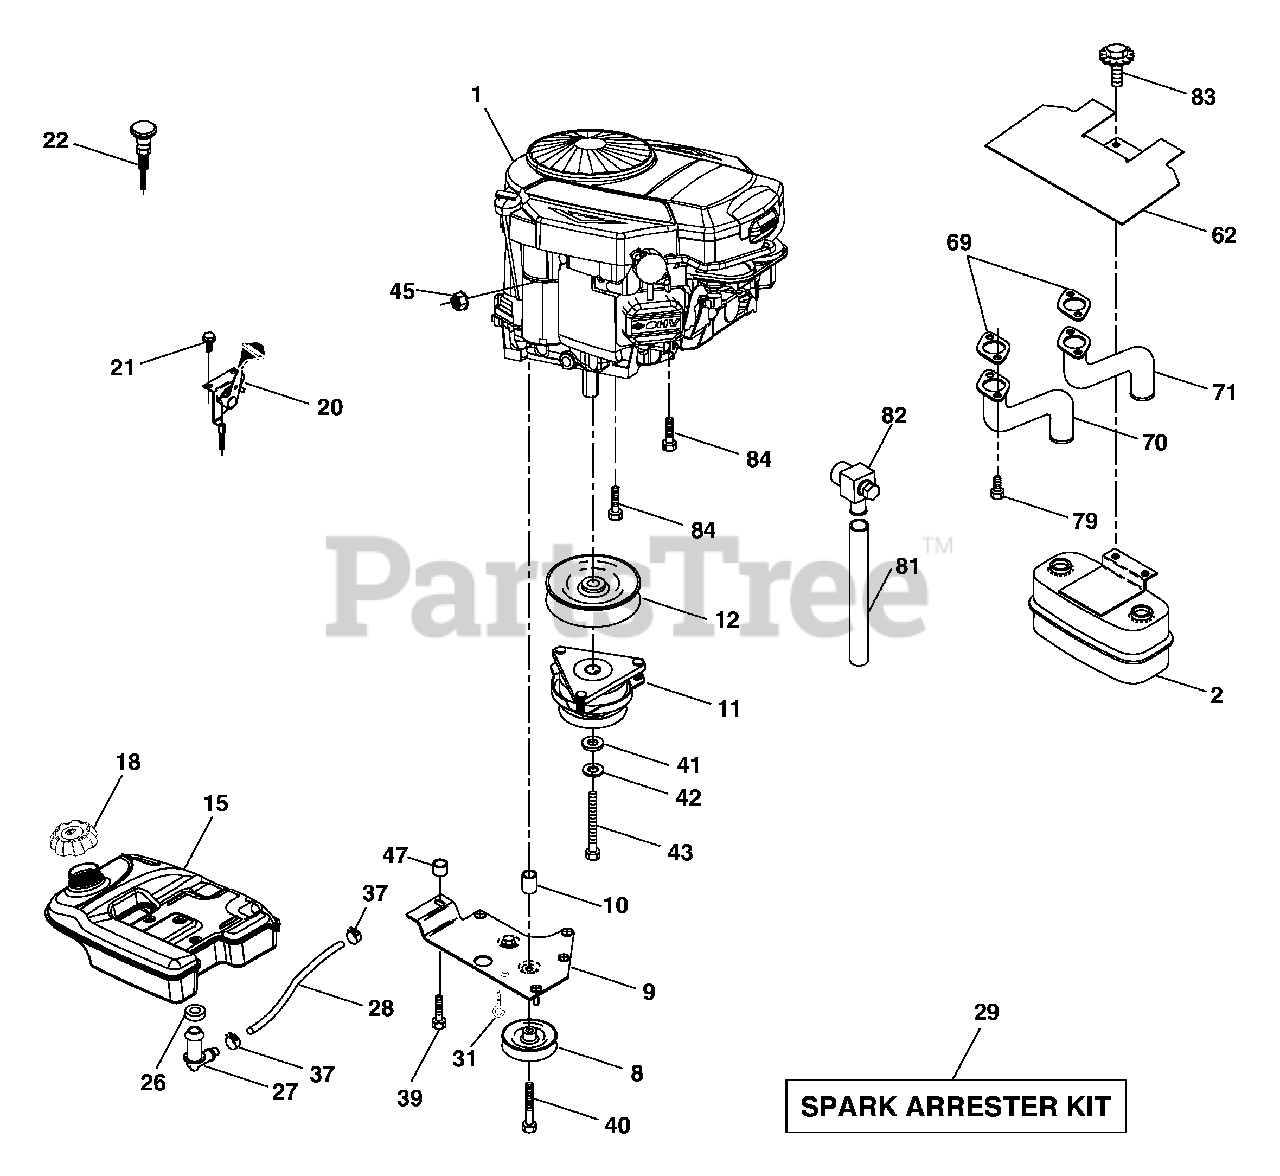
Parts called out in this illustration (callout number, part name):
2	Muffler Side
8	Pulley V-Idler
9	Keeper Asm. Belt Engine VGT
10	Bushing
11	Clutch
12	Pulley Engine VGT Elect Clutch
15	Tank Fuel Rear 5.0
18	Cap Asm. Fuel
20	Control Throttle
21	Screw 10 x 3/4 Single Hex
22	Control Choke
26	Bushing
27	Stem Tank Fuel
28	Fuel Line
29	Spark Arrester Kit
31	Clip Push-In Hinged
37	Clamp Hose
39	Screw TT 3/8-16 x 2-1/4 Unc
40	Screw TT 3/8-16 x 4 Unc
41	Washer 1-1/2 OD x 15/32 ID x .250
42	Washer Lock 7/16
45	Nut Keps Hex 1/4-20
47	Spacer
62	Shield Heat Muffler CV-Intek
69	Gasket
70	Tube Exhaust LH
71	Tube Exhaust RH
79	Screw Socket Head 5/16-18 x 1
81	Tube Drain Oil
82	Valve Oil Drain
83	Bolt 5/16-18 Unc x 1-3/4 W/Sems
84	Screw Thdrol 3/8-16 x 1-1/2
85	Bolt Hex 7/16-20 x 3.75 Gr. 5
